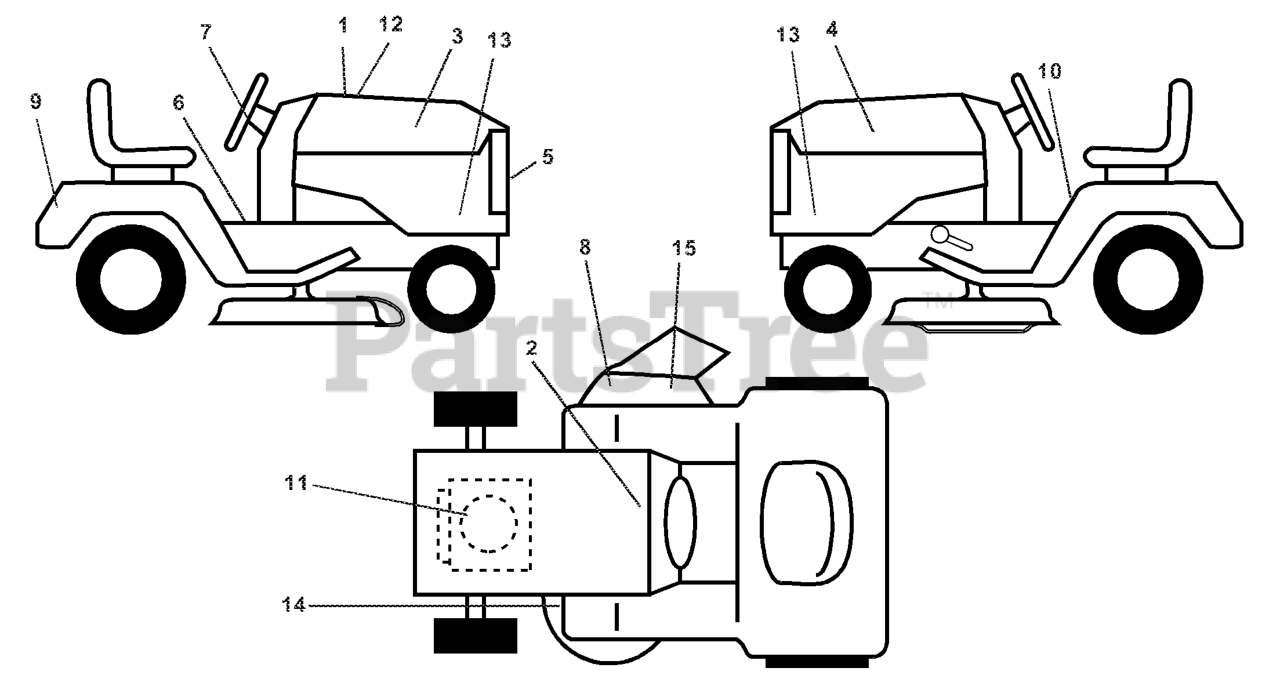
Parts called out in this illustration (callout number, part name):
1	DECAL HOOD CUST. RESP.
2	DECAL BTRY SYMBOLS
3	DECAL HOOD RH
4	DECAL HOOD LH
5	DECAL.GRILLE.HUSQ
7	DECAL.WHEEL.STEERING.HUSQ.PERM
8	DECAL.WARN.KEEP.HAND.AWAY
9	DECAL, FENDER
10	DECAL FENDER DANGER
11	DECAL ENGINE
12	DECAL HOOD
13	DECAL HOOD SIDES
14	DECAL V BELT SCHEMATIC
15	DECAL DECK "B" 42"
